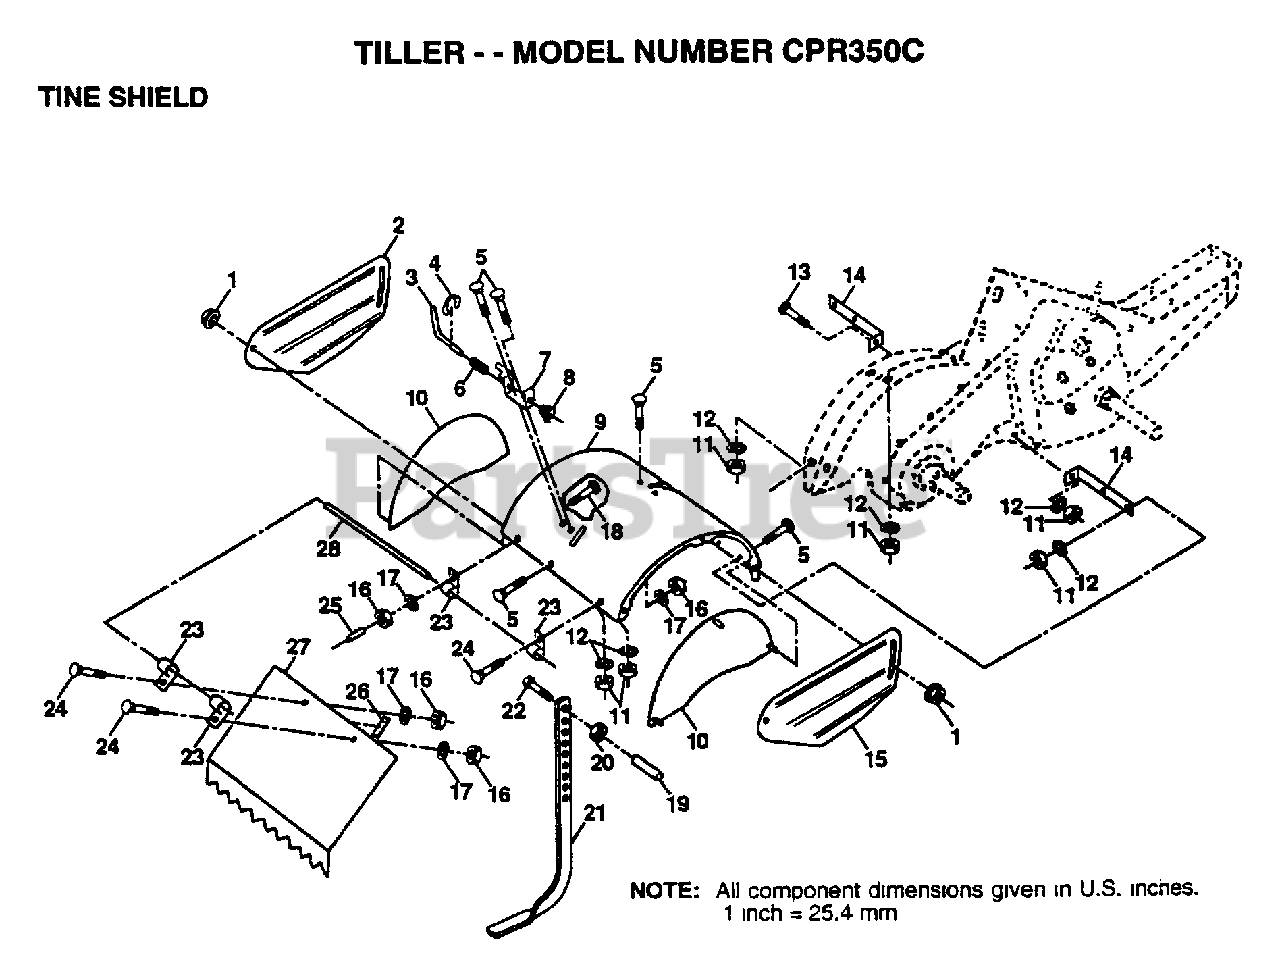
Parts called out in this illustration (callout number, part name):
1	NUT
2	SHIELD.SD.OUT.LH
3	STAKE PIN TI
4	KLIP RING TI
5	BOLT
6	SPRING TI
7	LATCH BRACKET TI
8	SPRING CRT
9	"SHIELD, TINE"
10	"SHIELD, SIDE"
11	NUT.HEX.5/16-18
12	LOCKWASHER
13	BOLT
14	BRKT SHIELD TINE
15	SHIELD.SD.OUT.RH
17	LOCKWASHER
18	BOLT
19	GRIP CRT
20	NUT.HEX.3/8-16UNC
21	STAKE DEPTH 16
22	BOLT
23	HINGE CRT
24	BOLT
25	VINYL CAP TI
26	PAD IDLER TI
27	LEVELING SHIELD
28	PIN HINGE
